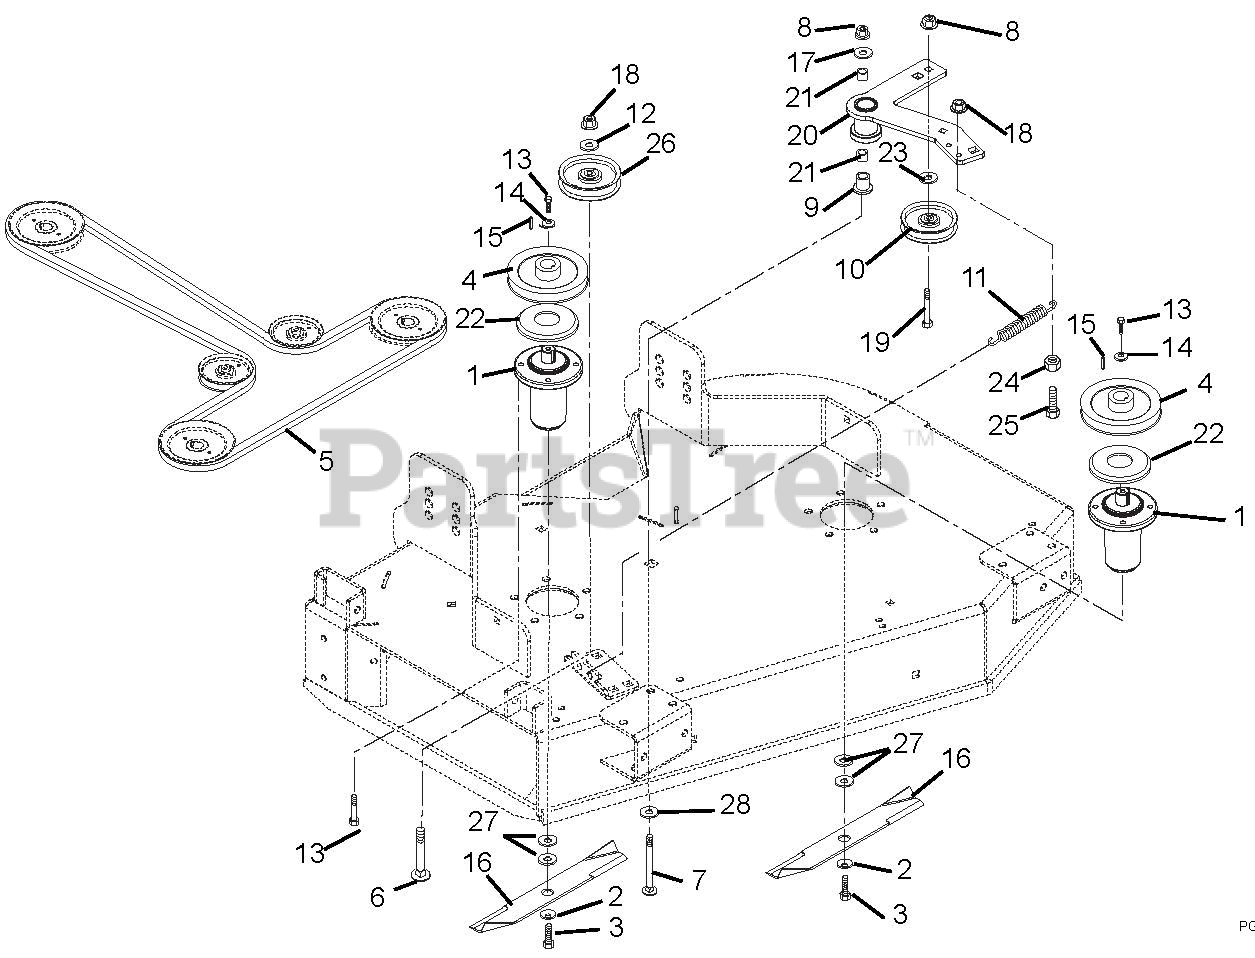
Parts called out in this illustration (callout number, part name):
1	Assembly, Spindle
2	Washer-Bellville .63 x 1.625 x .14
3	Bolt-Hex .62-18 x 1.75 Grade 8
4	Sheave, 5.00 Spindle, 1.00 I.D.
5	V-Belt, B-RMA 95" EFFLG x .650W
6	Bolt-Round Head Square Neck .38-16 x 2.75 Grade 5
7	Bolt-Round Head Square Neck .50-13 x 3.50 Grade 5
8	Nut-Locking-Top-Flange .50-13
9	Bearing, Pedestal Powdered Metal
10	Idler-Flat 6.75 x .510, 2.00 W
11	Spring, Extension
12	Washer-Flat-Steel .375 x 1.125 x .065
13	Bolt-Hex .38-16 x 1.00 Grade 8
14	Washer-Flat-Steel .406 x 1.50 x .245
15	Key, Square .25 x .25 x 1.00
16	Blade, Mower Hi -Lift
17	Washer-Flat-Steel .563 x 1.38 x .109
18	Nut-Locking-Top-Flange .38-16
19	Bolt, Hex .50-13 x 2.00 Grade 5
20	Weldment, Idler Pivot Arm
21	Bearing, 1.00 x 1.12 x .75
22	Slinger-Dust
23	Spacer, .516 x .875 x .300
24	Nut, Hex .38-16
25	Bolt, Hex .38-16 x 1.75
26	Idler-Flat 4.00 x .38
27	Washer, Flat .640 x 1.81 x .250
28	Washer, Flat Steel .755 x 1.375 x .062
